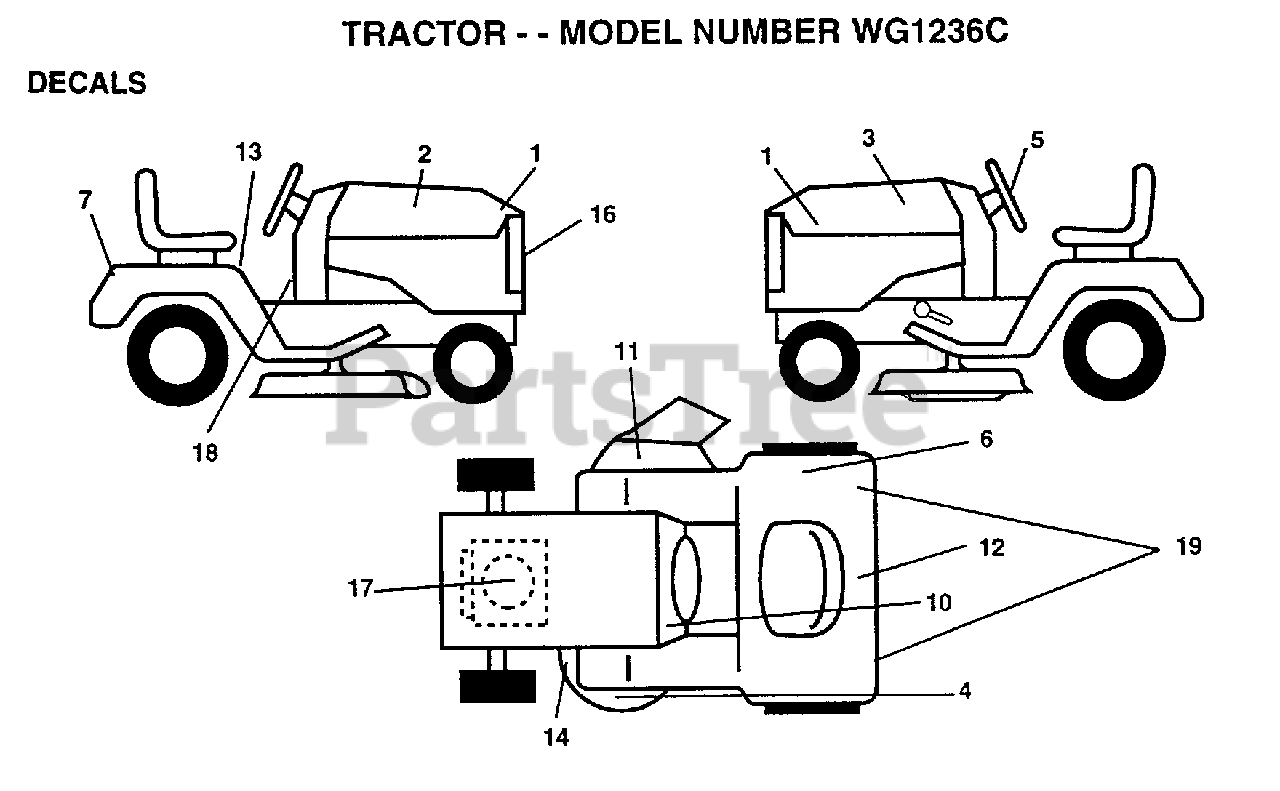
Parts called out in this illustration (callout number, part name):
1	DECAL PNL SIDE RH
2	DECAL STRIPE HOOD
3	DECAL STRIPE HOOD
4	DECAL.MOWER
5	DECAL.WHL.STRG.
7	DECAL.FENDER
10	DECAL.OP.INST.SYM
11	DECAL.INTERN.4SYM
12	DECAL.BTRY.DANGER
13	DECAL.READ.O.MANU
14	DECAL.V.BELT
16	"DECAL,LIGHT BOX"
17	DECAL, ENGINE
18	DECAL.EURO.ST.CE.
19	DECAL.FEND.QUICKS
